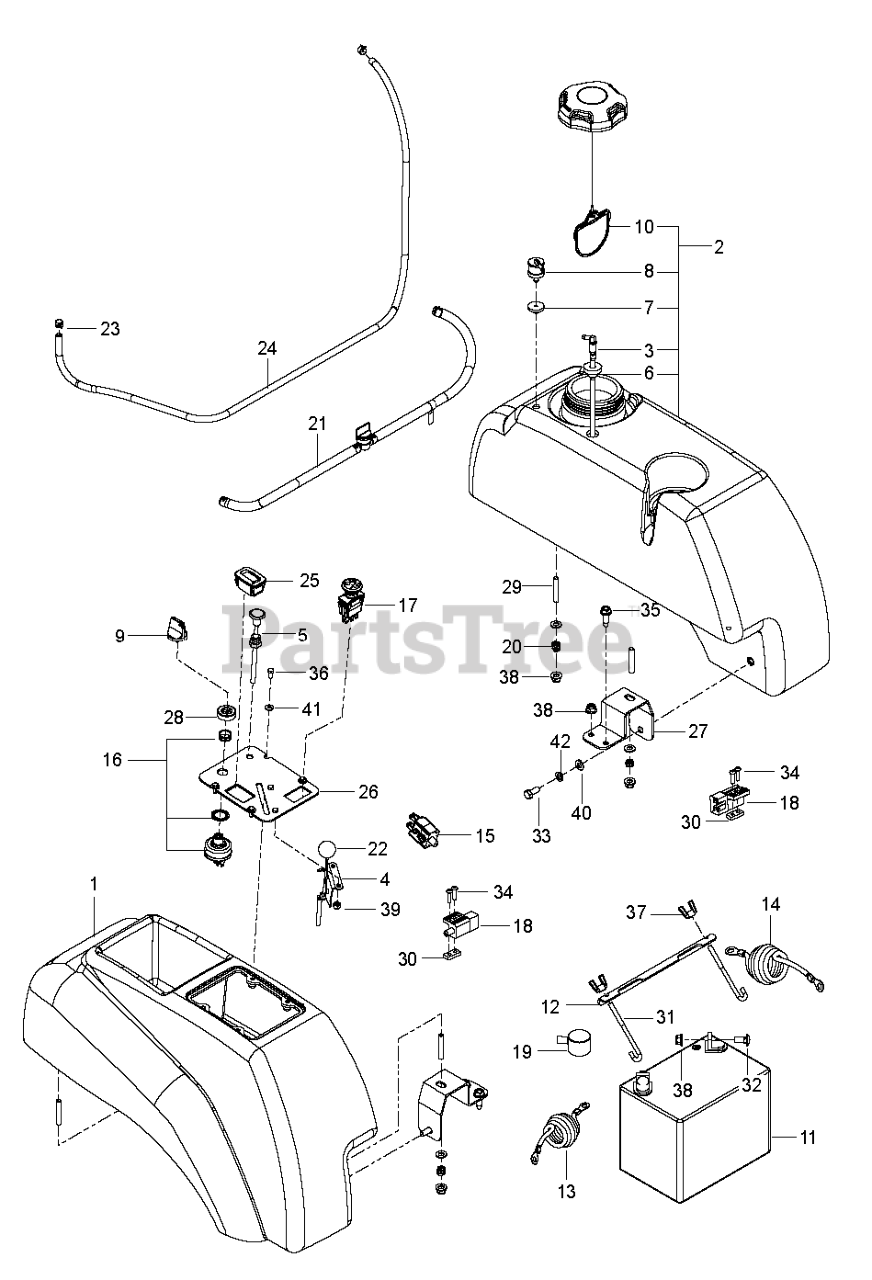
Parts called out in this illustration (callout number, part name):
1	FENDER CONSOLE
2	FUEL.TANK.ASSY.LH.MZ.GRY.17
3	FITTING, FUEL
4	THROTTLE CABLE
5	CABLE, CHOKE, 38
6	RUBBER GROMMET
7	GROMMET, CHECK VALVE
8	VALVE.FUEL.CHECK
9	KEY, IGNITION
10	CAP, FUEL
11	BATTERY, 12 V 330 AMP
12	BRACKET.BATTERY.MOUNT.PLATED
13	CABLE.BATT.SOLENOID.MZ.RED.25"
14	CABLE.GROUND.BATT.MZ.BLACK.39"
15	SWITCH.INTRLCK.CLUTCH.
16	SWITCH, IGNITION, INDAK
17	RP SWITCH.PTO.TERMINAL.STD.RED
18	SWITCH INTERLOCKT
19	COVER.TERMINAL.BATTERY
21	FUEL.HOSE.SHUT.OFF.ASM.10".10"
22	KNOB.ROUND.BALL.BLACK
23	CLAMP, HOSE
24	HOSE.3/16".VAPOR.LINE.27"LGTH
25	GUAGE.SRVCMNDR.HRMTR.
26	PLATE, CONSOLE, BLK
27	SUPPORT, TANK, BLK
28	CAP IGNITION NUT
29	STUD, 5/16C
30	PLATE NUT ZTR
32	BOLT 5/16C X 3/4" CARRIAGE
33	HCS 5/16C X 3/4
34	SCR #10-24 X .75 SKT HD BLK
35	HCS #10-24 X 1/2
36	SCREW
37	WING NUT 1/4
38	5/16-18 NYLOC FLANGE NUT
39	NUT 10-24 NYLOC
40	WASHER
42	WASH.5/16.SLW.ZD
